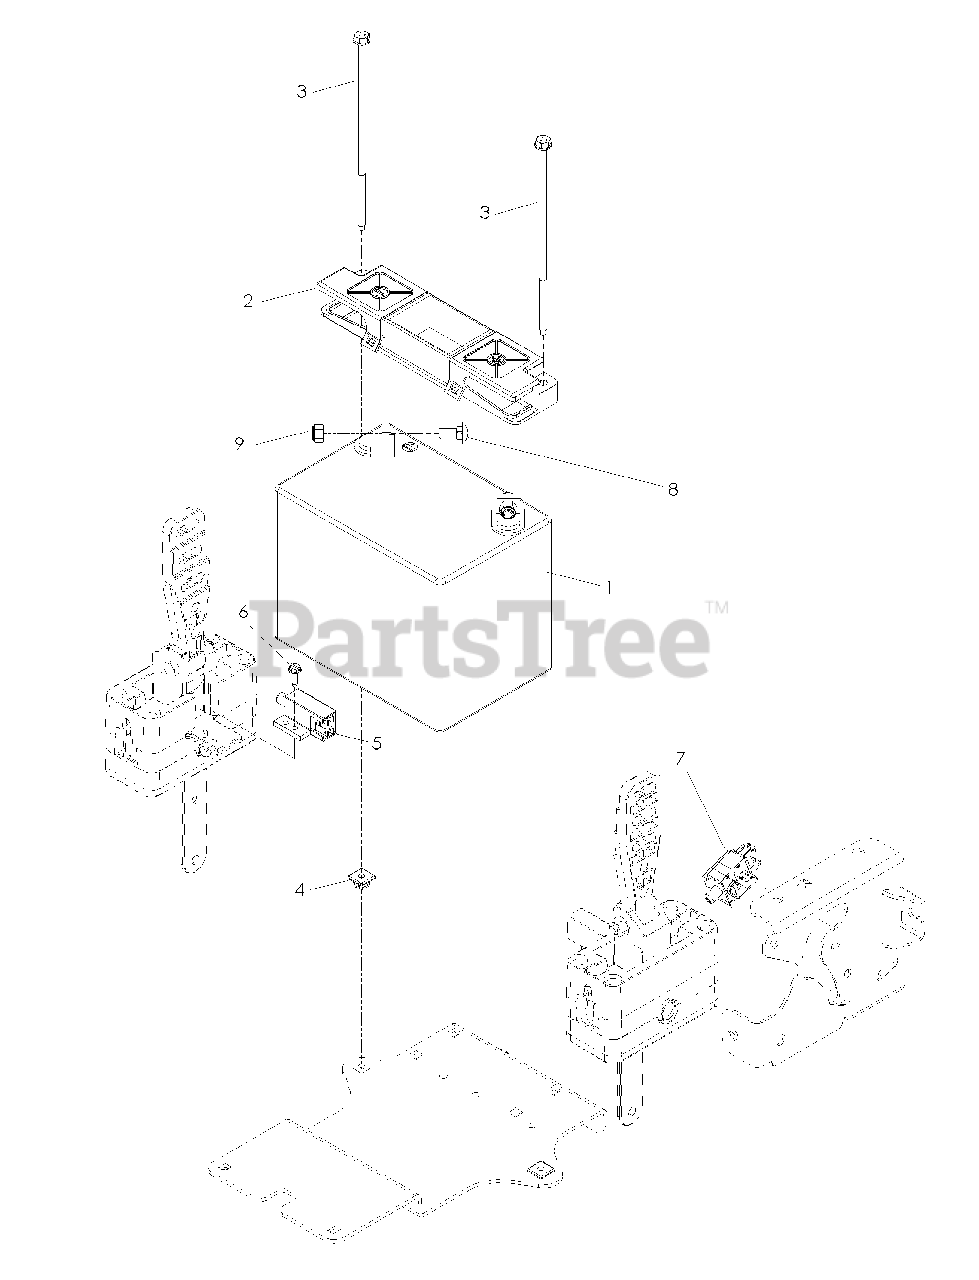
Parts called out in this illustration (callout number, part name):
1	BATTERY
2	BATTERY HOLD DOWN
3	BOLT, 1/4 x 7 1/2
4	NUT 1/4 PUSH, NYLON
5	SWITCH, INTERLOCK
6	SCREW #10-24 x 5/8 WSH HD
7	SWITCH, BRAKE
8	BOLT, 5/16-18 x 3/4
9	NUT 5/16-18 FLANGE NYLOC
